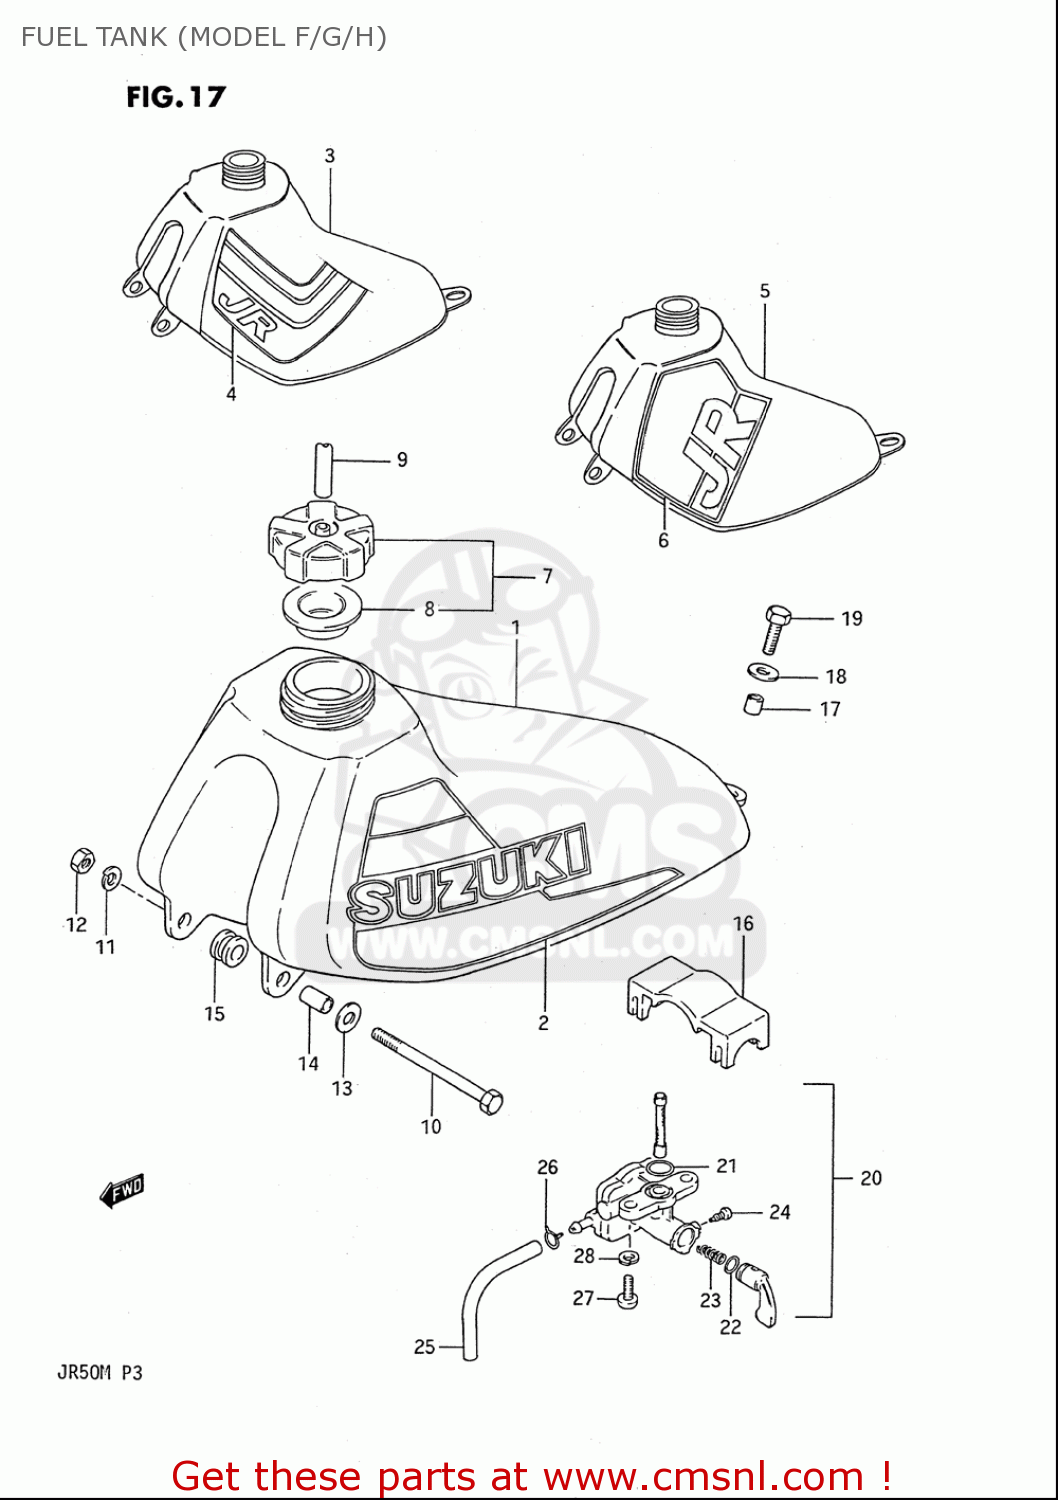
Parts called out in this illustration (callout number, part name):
3	TANK,FUEL
7	CAP SET,FUEL TANK
8	GASKET (NAS)
9	HOSE(5X8.2X600)
10	BOLT
11	WASHER,LOCK
12	NUT
13	WASHER(6.5X18X1)
14	SPACER (6.8X10X11.5)
15	CUSHION
16	CUSHION,FUEL TANK UPR
17	SPACER(6.5X9X7.2)
18	WASHER(6.5X18X1)
19	BOLT
20	COCK ASSY,FUEL
21	O RING
22	O RING,LEVER
23	SPRING
24	SCREW
25	HOSE(5X8.2X600)
26	CLIP
27	SCREW
28	WASHER,LOCK
